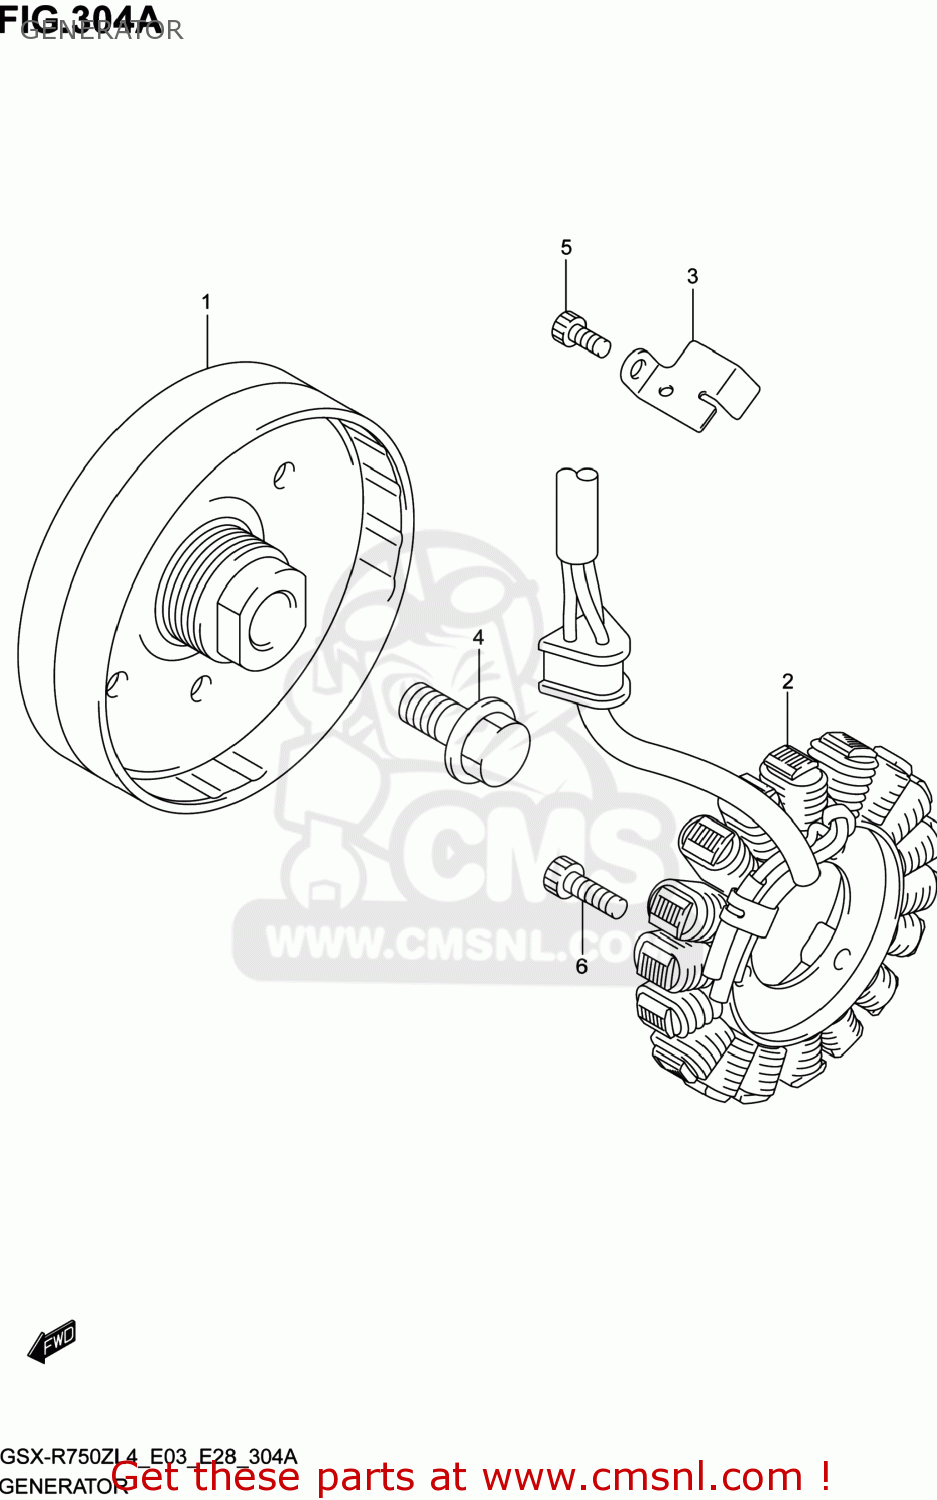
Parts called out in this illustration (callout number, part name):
1	ROTOR ASSY
2	STARTER ASSY
3	CLAMP,GENERATOR LEAD WIRE
4	BOLT,GENERATOR ROTOR
5	BOLT
6	BOLT
